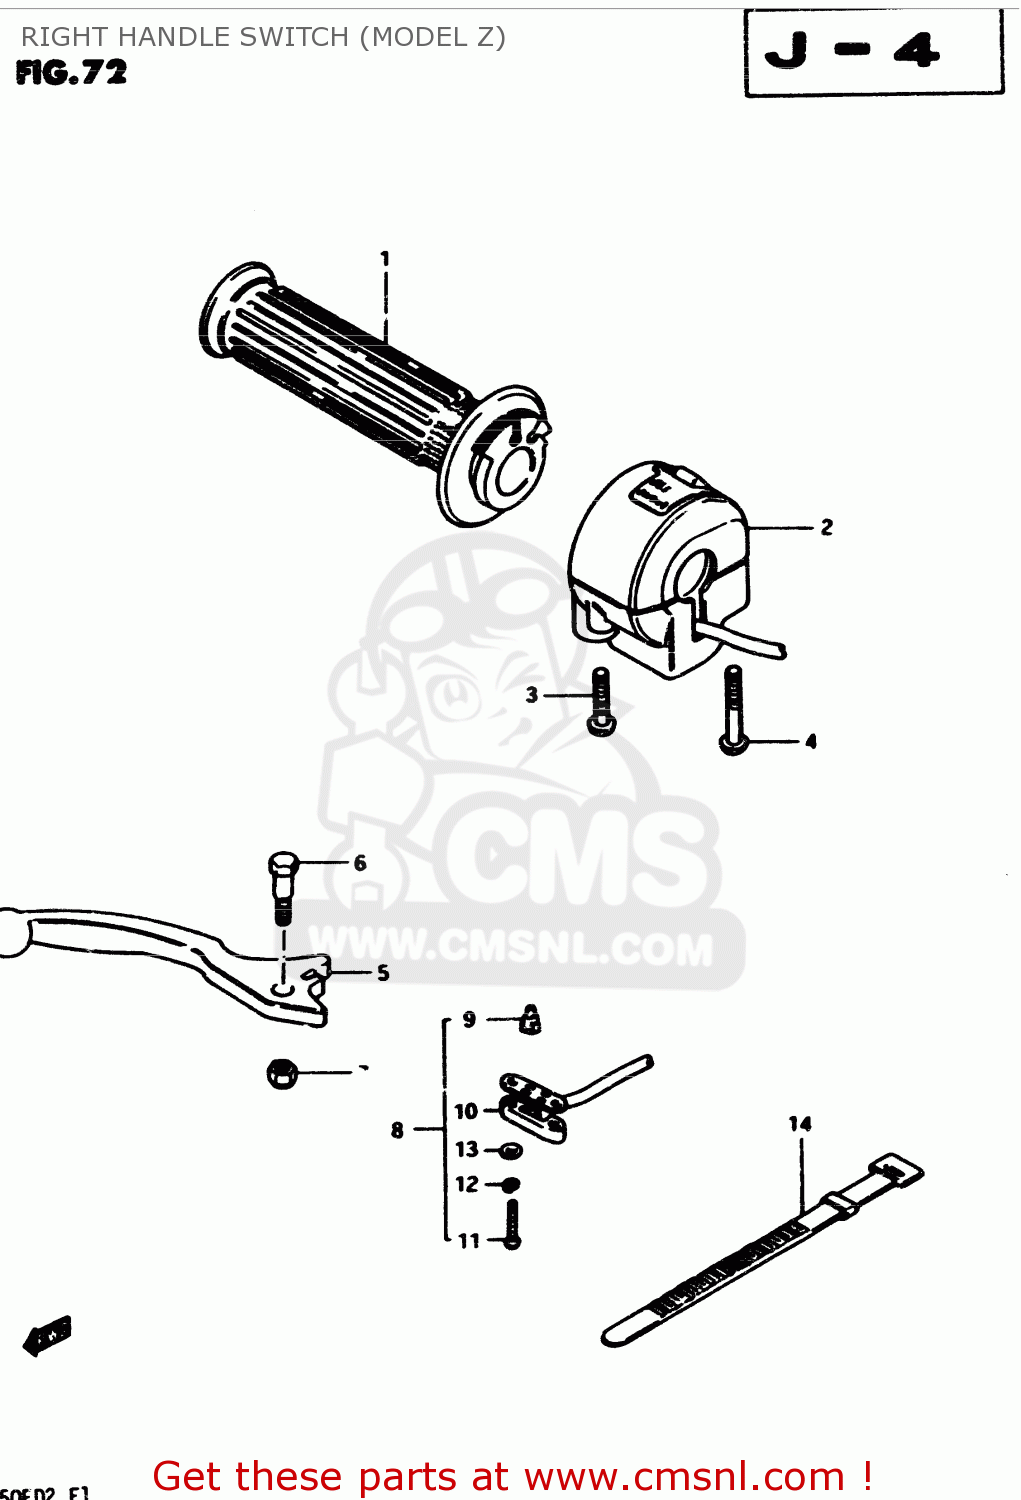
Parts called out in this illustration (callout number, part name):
1	GRIP,THROTTLE
2	SWITCH ASSY, HANDLE LH
3	SCREW
4	SCREW
5	LEVER,BRAKE
6	BOLT
7	NUT 6MM
8	SWITCH ASSEMBLY
9	CONTACT,SWITCH
10	COVER,FR BK TERMINAL BASE
11	SCREW
12	LOCK WASHER
13	WASHER
14	CLAMP(L:120)
